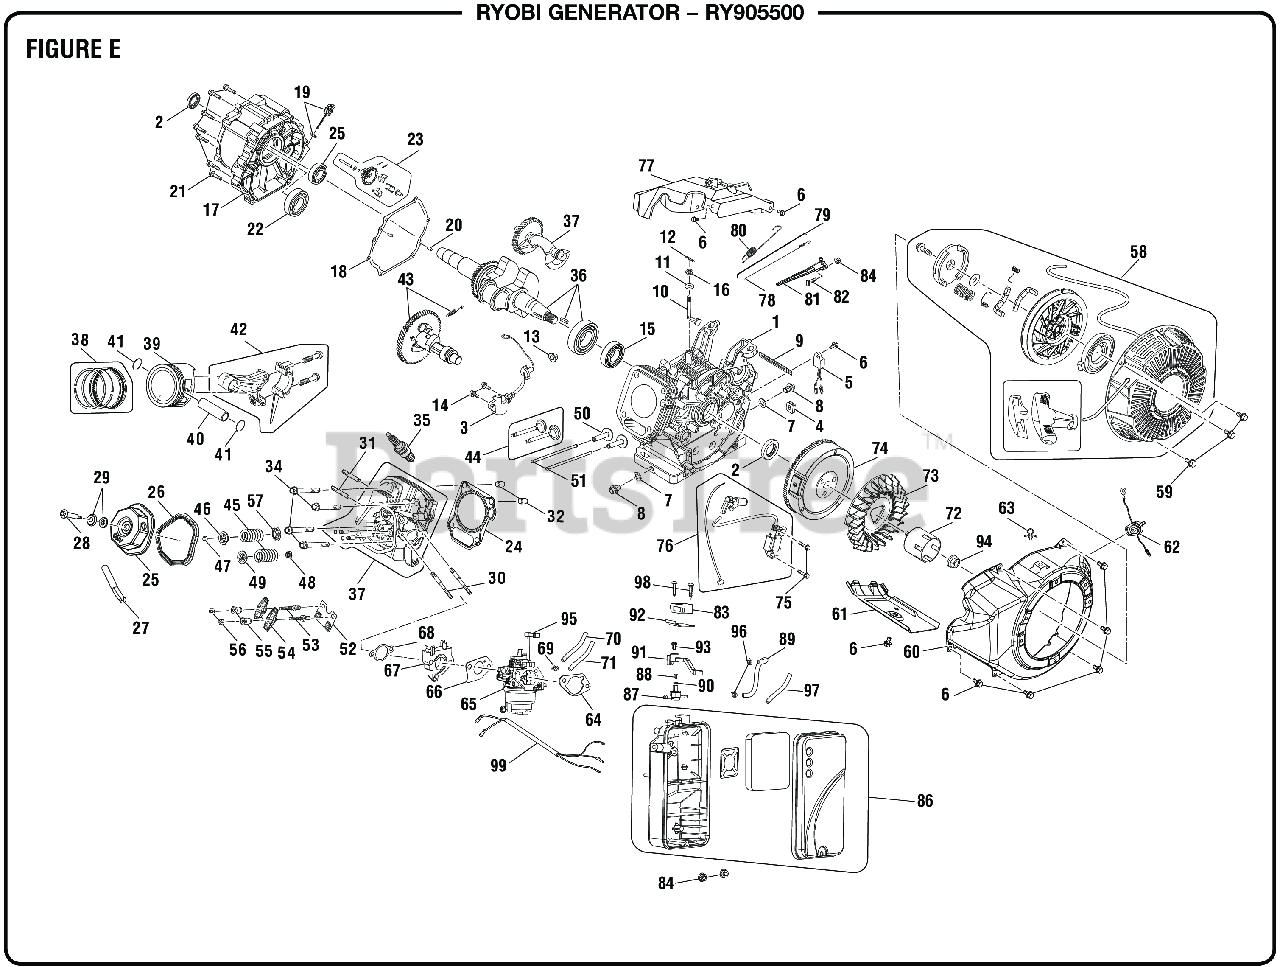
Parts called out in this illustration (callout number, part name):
3	Engine Oil Sensor
6	Bolt (need size)
7	Drain Plug Washer
8	Drain Plug Bolt
15	Ball Bearing
17	Crankcase Cover
18	Crankcase Gasket
19	Oil Filler Cap (Yellow)
23	Governor Gear Assembly
24	Cylinder Head Gasket
25	Cylinder Head Cover Assembly
26	Cylinder Head Gasket
28	Cylinder Head Cover Bolt
33	Cylinder Head Bolt
35	Cylinder Head Assembly
36	Crankshaft Assembly
37	Balancing Shaft
38	Piston Rings Set
41	Piston Pin Clip
43	Camshaft Assembly
46	Exhaust Valve Retainer
49	Valve Spring Retainer
52	Lifter Stopper Plate Assembly
53	Valve Adjustment Bolt
55	Valve Adjustment Nut
57	Valve Spring Retainer
58	Recoil Starter Assembly
61	Cylinder Shroud
62	Stop Engine Switch Assembly
64	Air Cleaner Gasket
65	Carburetor Assembly
66	Carburetor Gasket
67	Carburetor Insulator
68	Insulator Gasket
74	Flywheel Assembly
77	Throttle Control Assembly
78	Throttle Valve Return Spring
80	Governor Spring
81	Governor Support Assembly
82	Governor Support Bolt,
83	Enginge Stop Switch
84	Governor Support Assembly
85	Air Cleaner Bottom Cover
87	Fuel Valve
88	Screw (M4 x 10 mm, Phillips Pan Hd.)
89	Fuel Hose (330 mm)
90	Washer (ID4.3 x OD10 x 0.9t)
91	Control Lever (Grey)
92	Engine Switch Bracket
93	Bolt (M6 x 10 mm, Pan Hd)
95	Choke Lever (Grey)
96	Clamp (D7 x 0.8 mm)
98	Screw (St 2.9 x 16 mm, Pan Hd)
99	Micro Switch Wiring
